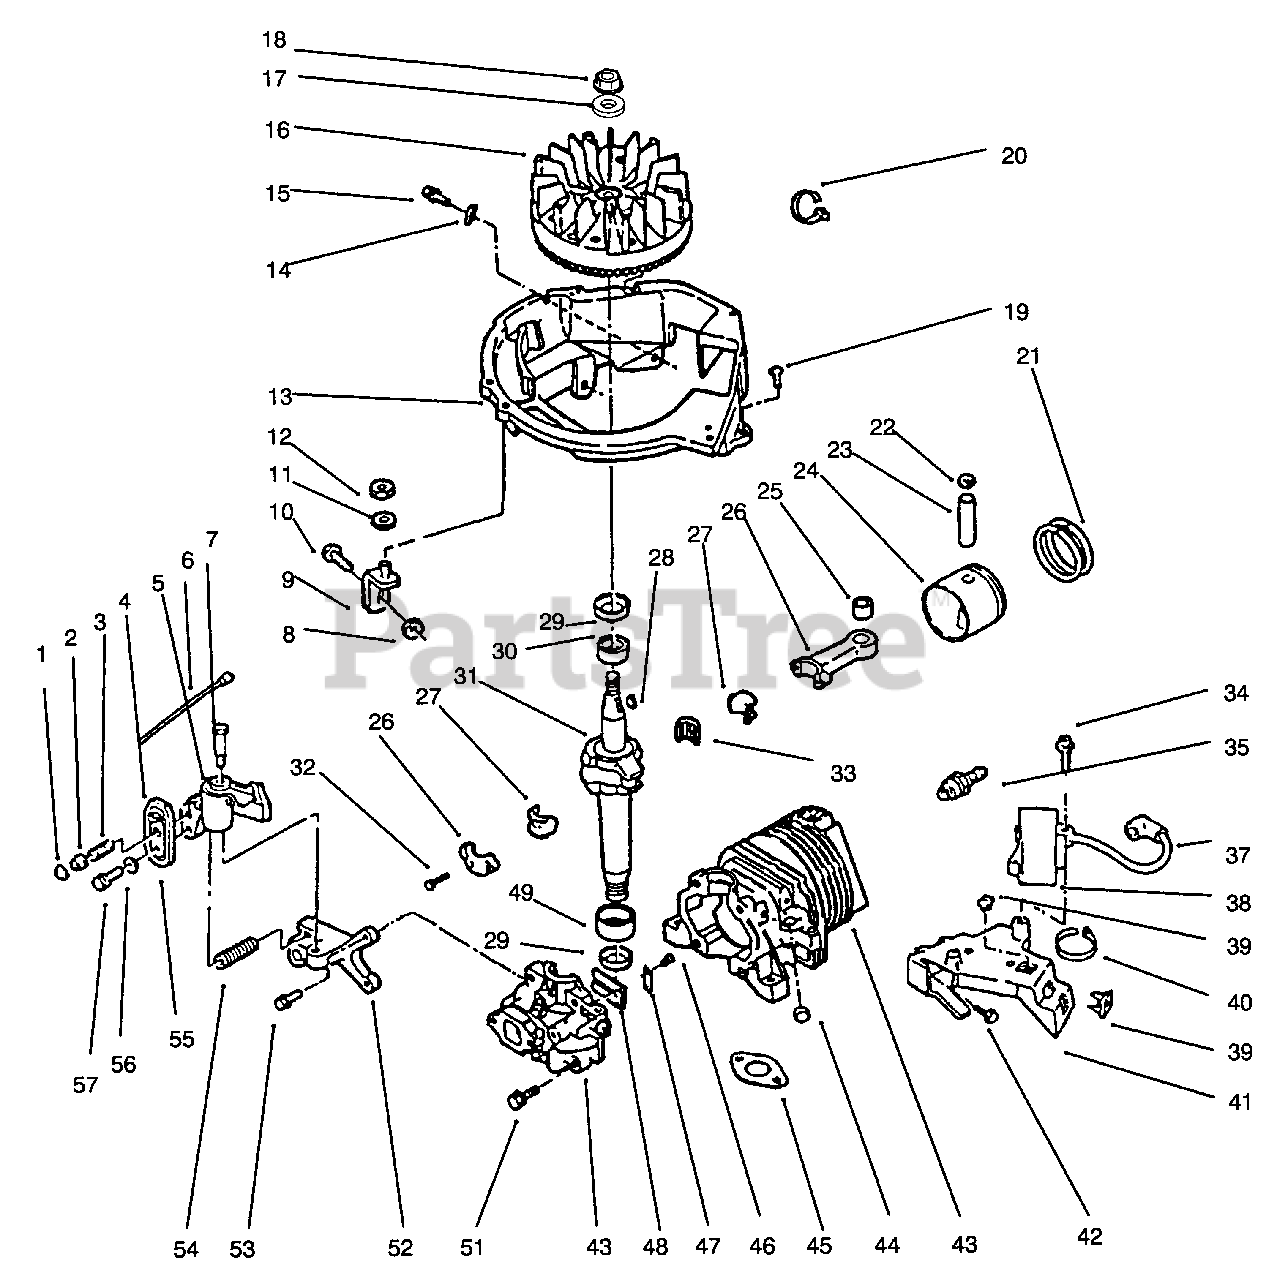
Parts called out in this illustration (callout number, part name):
1	Retainer
2	Actuator-Brake Lever
3	Spring-Cable, Return
4	Assembly-Switch (Incl. Ref. #1, 6, 20, & 55-57)
5	Assembly-Brake
6	Wire Lead
7	Bolt-Shoulder
9	Assembly-Brace
11	Washer
13	Shroud-Base
14	Clip-"J"
16	Assembly-Flywheel
17	Washer-Lock
18	Nut-Flywheel
20	Tie Strap
21	Ring-Piston
22	Ring-Retaining
23	Pin-Wrist
25	Assembly-Bearing
26	Assembly-Conn. Rod (Incl. Ref. #25-27 & 32-33)
27	Liner-Split
28	Key-Flywheel
29	Seal-Oil
30	Bearing-Main
31	Crankshaft
33	Set-Needle Bearing
34	Screw
35	Spark Plug
37	Wire Lead
38	C. D. lgnition Module (Incl. Ref. #37)
39	Nut-Speed
40	Tie Strap
41	Bracket-C.D.
43	Assy.-Cyl./Crankcase Cover (Incl. Ref. #44, 46-48, 51 & 53)
45	Gasket-Exhaust
47	Plate-Reed
49	Bearing-Main
52	Bracket-Brake
54	Spring-Brake
55	Assembly-Case
56	Washer
57	Screw
